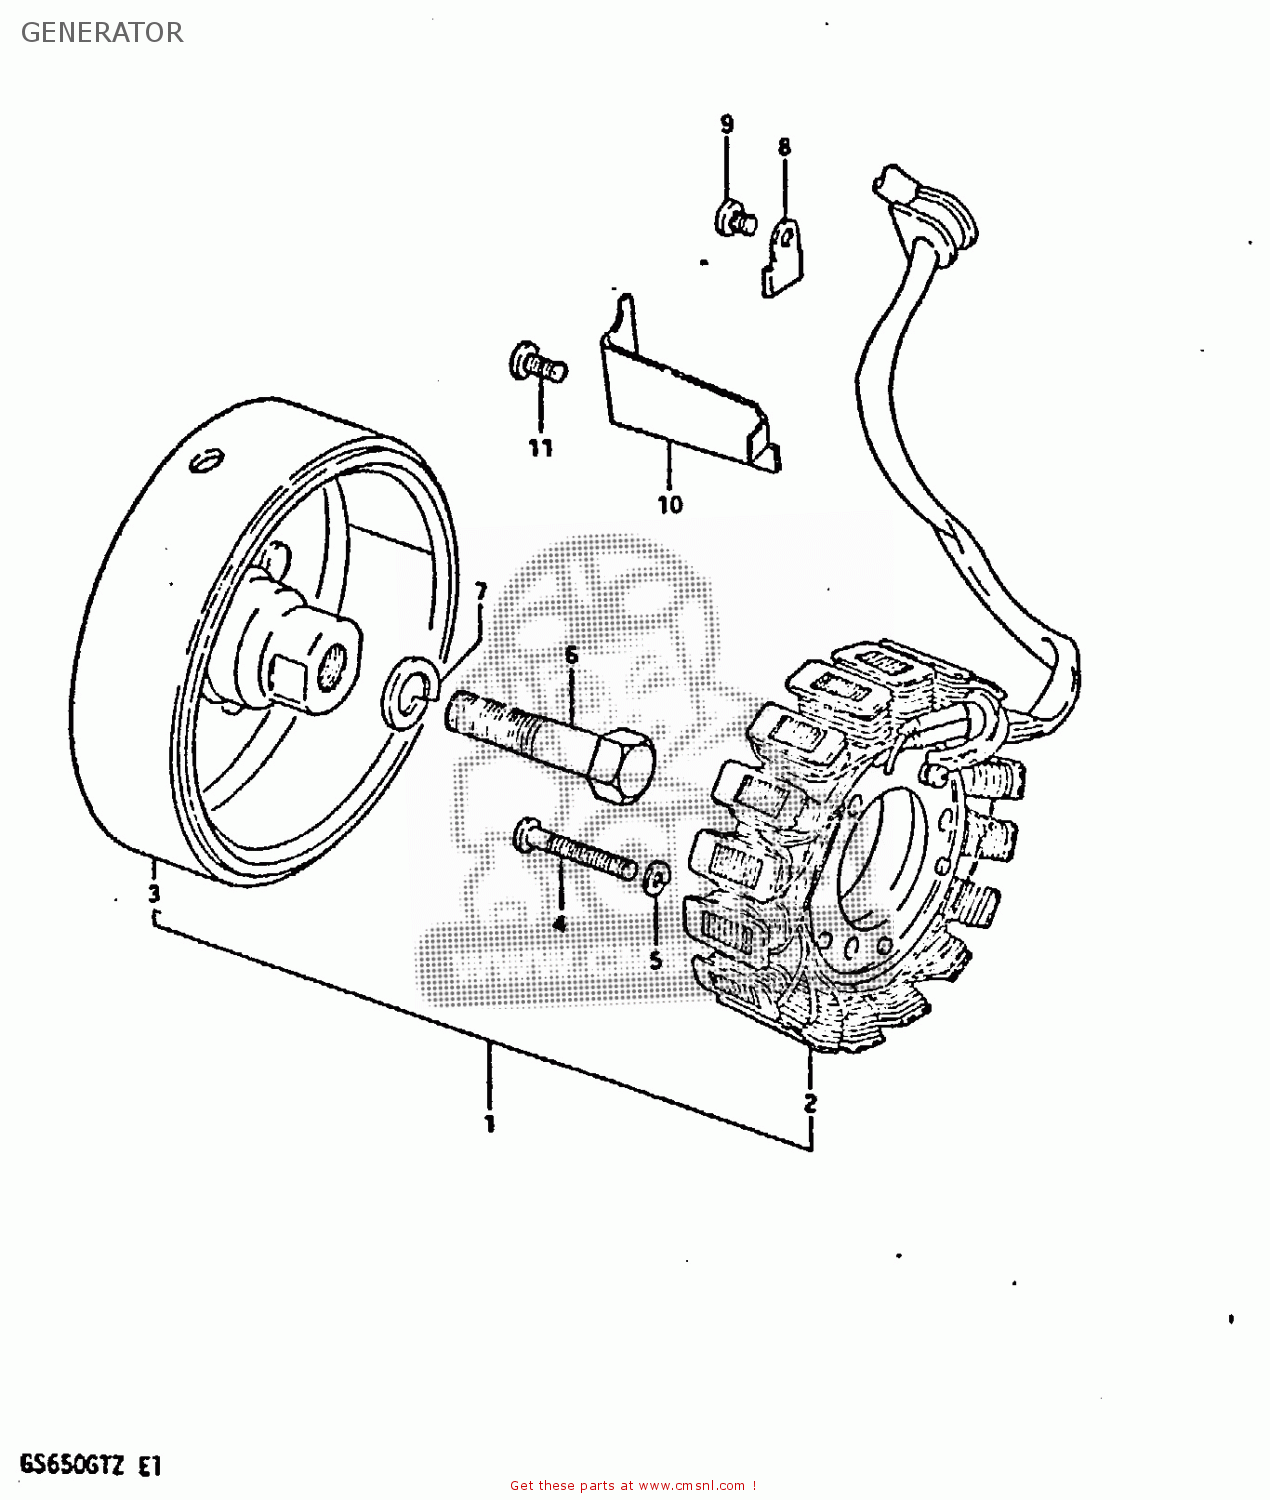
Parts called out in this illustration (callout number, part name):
1	GENERATOR ASSEMBLY
2	STATOR ASSEMBLY
3	ROTOR ASSEMBLY
4	SCREW
5	LOCK WASHER
6	BOLT 12X45
7	WASHER,LOCK 12
8	CLAMP,GENERATOR LEAD WIRE
9	SCREW
10	CLAMP,GENERATOR LEAD WIRE
11	SCREW
